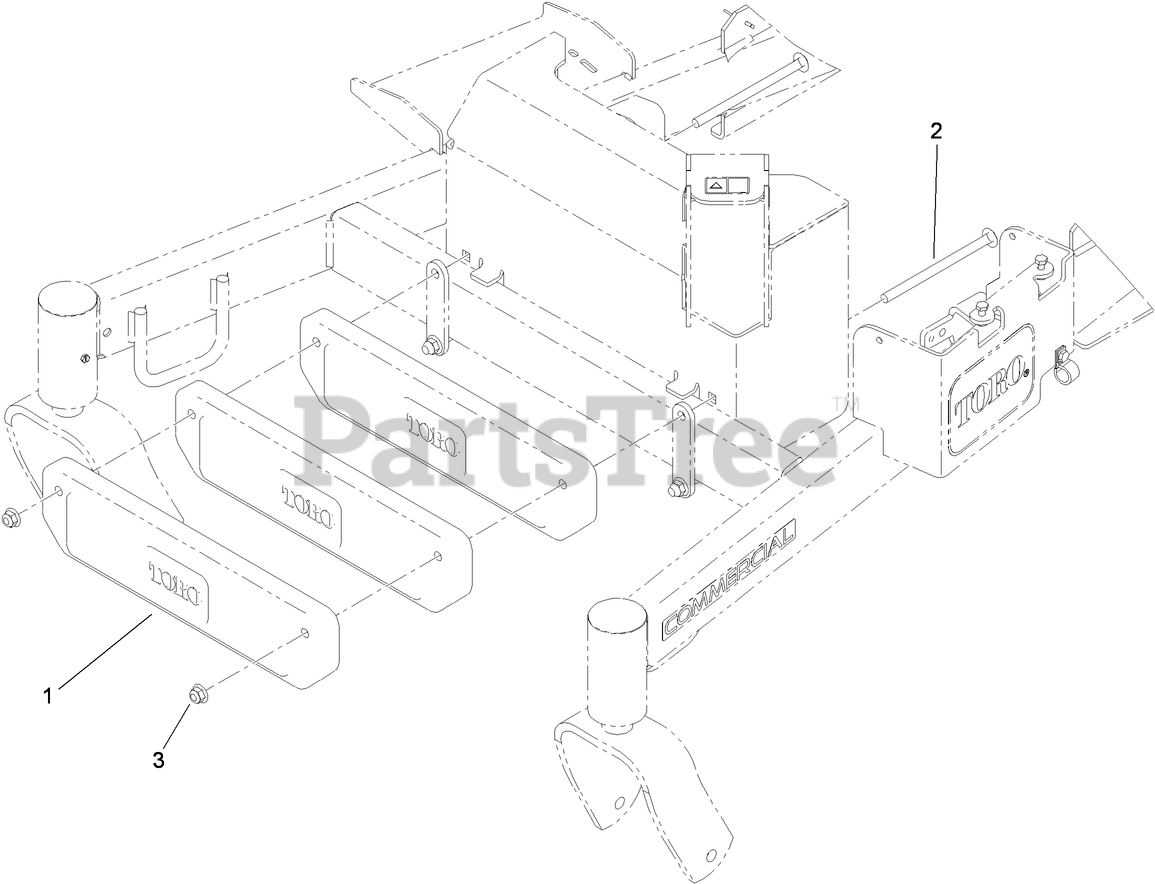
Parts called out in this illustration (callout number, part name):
1	WEIGHT-CAST
2	BOLT-CARR
2	BOLT-CARR, 4 INCH
2	BOLT-CARR, 6 INCH
3	NUT-HF, NI
